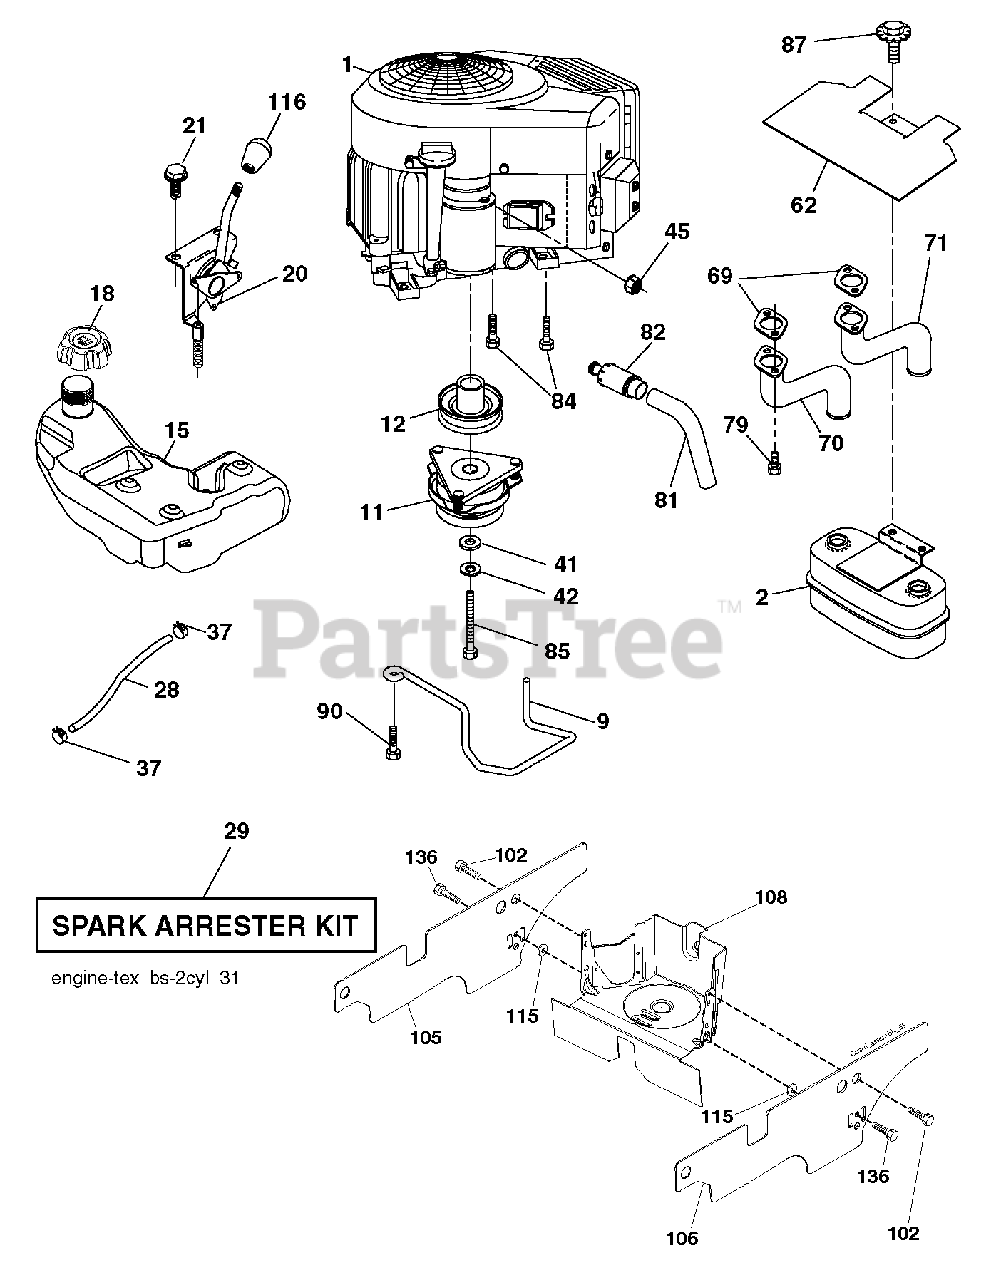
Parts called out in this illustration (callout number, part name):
2	MUFFLER.ASM.TWN.EXTNDED.DFLCTR
9	KEEPER BELT ENGINE
11	RB.CLUTCH.OGURA.4.4.PD
12	PULLEY.ENGINE.TUFFTORQ
15	TANK.FUEL.4GAL
18	CAP.ASSY.FUEL.3".N-EPA.GRY.498
20	CONTROL.THROTTLE/CHOKE.PRO.45
21	SCREW.#10 X 0.750.BOS
28	REPL BY 532 00 85-43
29	KIT.SPARK ARRESTOR 794945 B&S
37	HOSE CLAMP
42	LOCKWASHER
45	NUT
62	SHIELD.HEAT.MUFFLER
69	GASKET.MUFFLER
70	EXHAUST.TUBE.LH.BS/TWIN
71	EXHAUST.TUBE.RH.B&S.TWIN.INTEK
79	SCREW.SOCKET.HEAD.5/16-18
81	TUBE, DRAIN OIL ASM.
82	VALUE.OIL.DRAIN
84	SCREW.3/8-16
85	BOLT HEX 7/16-20X4-1/4"
87	BOLT, 5/16-18 X 1 3/4
90	SCREW 3/8-16X1
102	SCREW
105	SHIELD.SIDE.LH.3842"TEX FRENCH
106	SHIELD.SIDE.RH.3842"TEX FRENCH
108	ENGINE COVER
115	PALNUT 1/4
116	KNOB - SHIFT
136	SCREW.1/4-20X5/8
